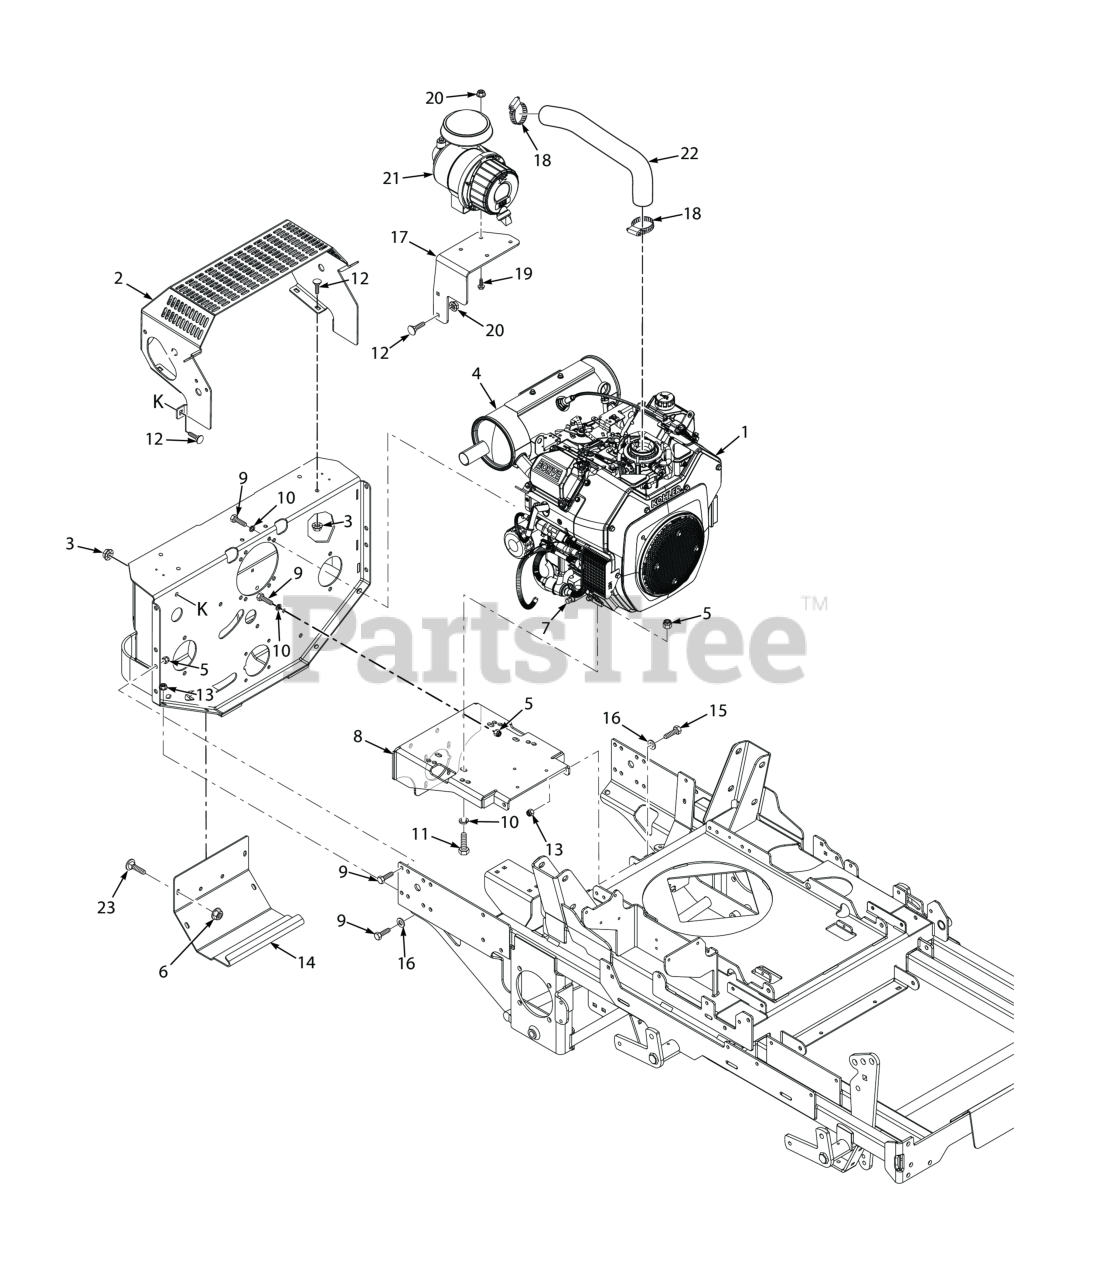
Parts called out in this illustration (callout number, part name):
1	Engine, 25 LP-EFI - Kohler
2	Guard, Muffler
3	Nut, Flange Head Elastic Stop 5/16-18
4	Muffler, 25 LP-EFI - Kohler
5	HEX NUT, ELASTIC STOP LOCK, 3/8-16
6	Nut, Serrated Flange 5/16-18 (Right Front Engine Mounting, Briggs and Kohler Only)
7	Oil Drain, Kohler 25 LP-EFI
8	Plate Weldment, Engine Mounting
9	Bolt, Hex Head, 3/8-16 x 1 Gr. 5
10	Lockwasher, 3/8" Spring, Kawasaki FX / FT & FT-EFI / B&S 32BV
11	Bolt, Hex Head 3/8-16 x 1-3/4" (Kohler EFI)
12	Bolt, 5/16-18 x .75 RHSN Carriage
13	Nut, Flange Elastic Stop Nut, 3/8-16
14	Cover, Rear
15	Bolt, Hex Head 3/8-16 x 1-1/4", Kawasaki FX / FT & FT-EFI
16	Flatwasher, 3/8" Special (.391 x .938 x .105)
17	Bracket, Air Cleaner Mount
18	Clamp, 2-3/4" Max. Dia.
19	Cpscrw, 5/16-18 x 1"Serrated Flange Hex Head
20	Nut, Serrated Flange 5/16-18 (Right Front Engine Mounting, Briggs and Kohler Only)
21	Air Filter Assembly
22	Hose, Air Intake
23	Bolt, Carriage 1/4-20 x 1/2"
